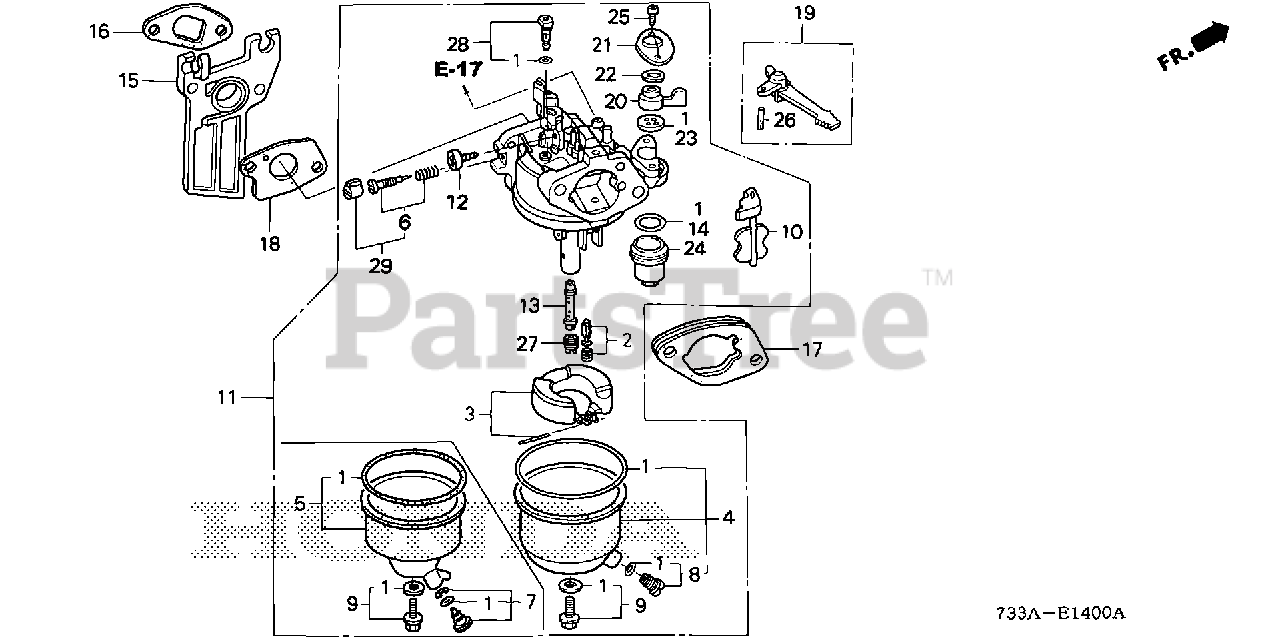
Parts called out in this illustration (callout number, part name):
1	GASKET SET
2	VALVE SET, FLOAT (SEAT NOT INCLUDED)
5	CHAMBER SET, FLOAT (CARBURETOR NO.)
5	CHAMBER SET, FLOAT
7	SCREW SET, DRAIN
9	SCREW SET
11	CARBURETOR ASSY. (BE60G B)
12	SCREW, THROTTLE STOP
13	NOZZLE, MAIN
14	GASKET, FUEL STRAINER CUP
15	INSULATOR, CARBURETOR
16	GASKET, INSULATOR
17	SPACER, CARBURETOR
18	GASKET, CARBURETOR
19	LEVER, CHOKE (STD)
20	LEVER, PETCOCK
21	PLATE, LEVER SETTING (CARBURETOR NO.)
22	SPRING, PETCOCK LEVER (CARBURETOR NO.)
23	GASKET, PETCOCK (CARBURETOR NO.)
24	CUP, FUEL STRAINER
25	SCREW, PAN (3X8) (CARBURETOR NO.)
25	SCREW, PAN (3X6)
26	PIN, SPRING (2X12)
27	JET, MAIN (#58)
27	JET, MAIN (#60)
27	JET, MAIN (#62)
28	JET SET, PILOT (#35)
29	SCREW SET, PILOT (CARBURETOR NO.)
